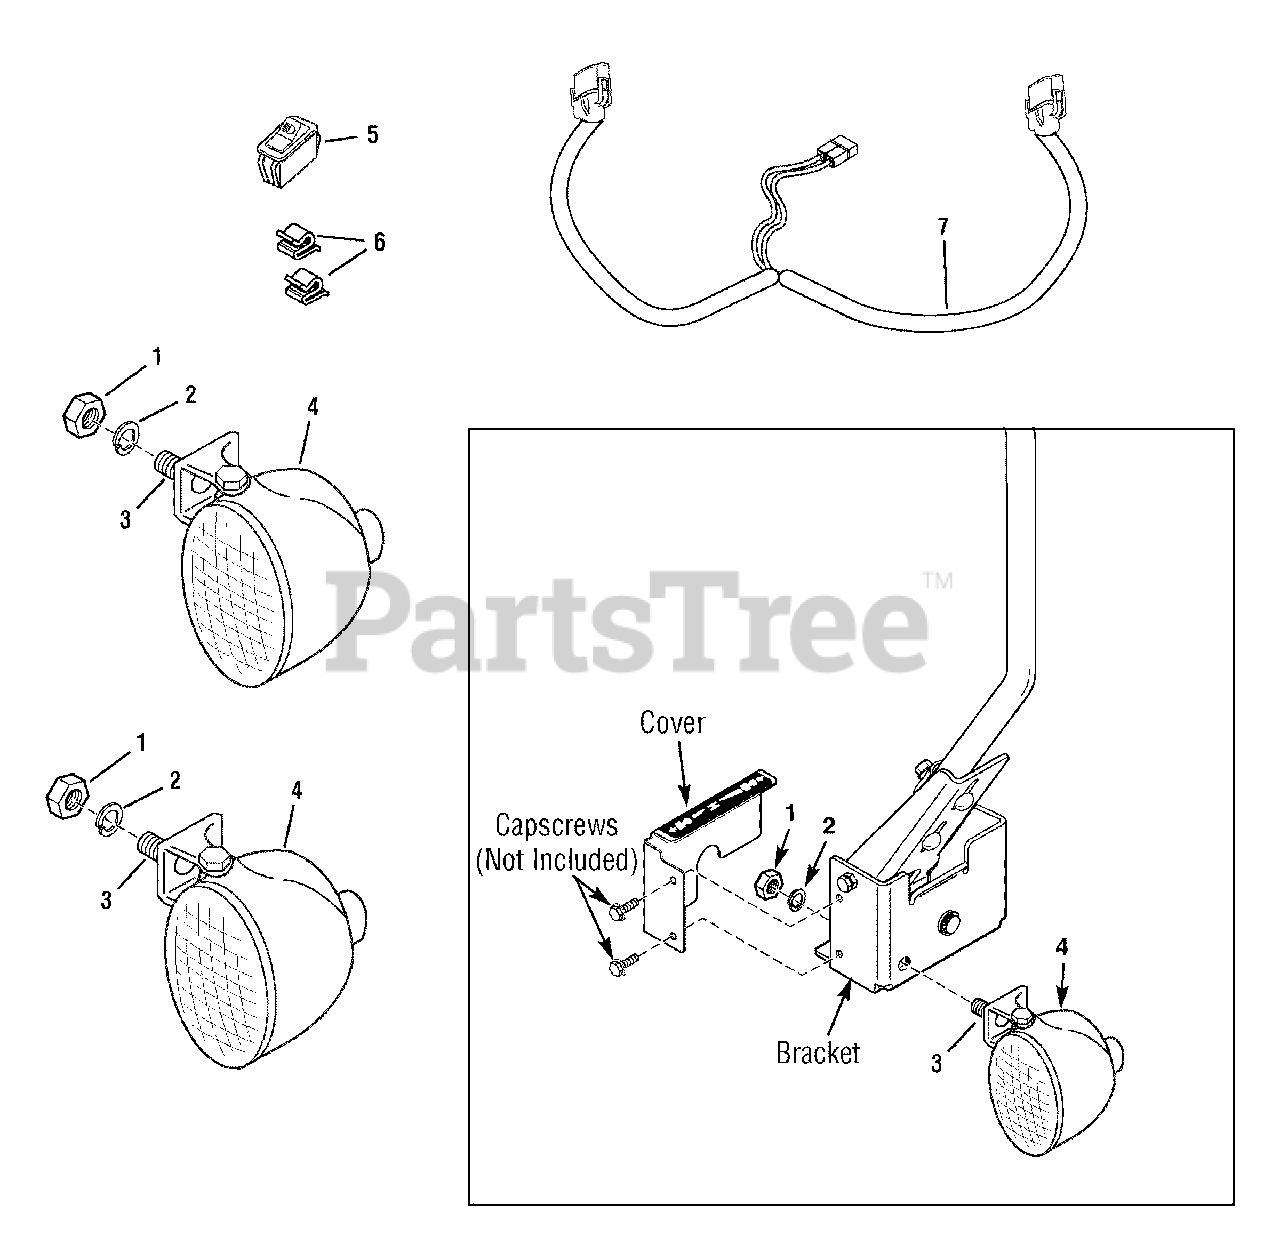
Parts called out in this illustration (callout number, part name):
1	NUT, Hex Lock, Nylon Insert, 5/16-18
2	WASHER, Lock Helical Spring
3	BOLT, Carriage, 5/16-18 x 1
4	HEADLIGHT ASSEMBLY
5	SWITCH, Headlights
6	CLIP, Wire
7	HARNESS, Wire
